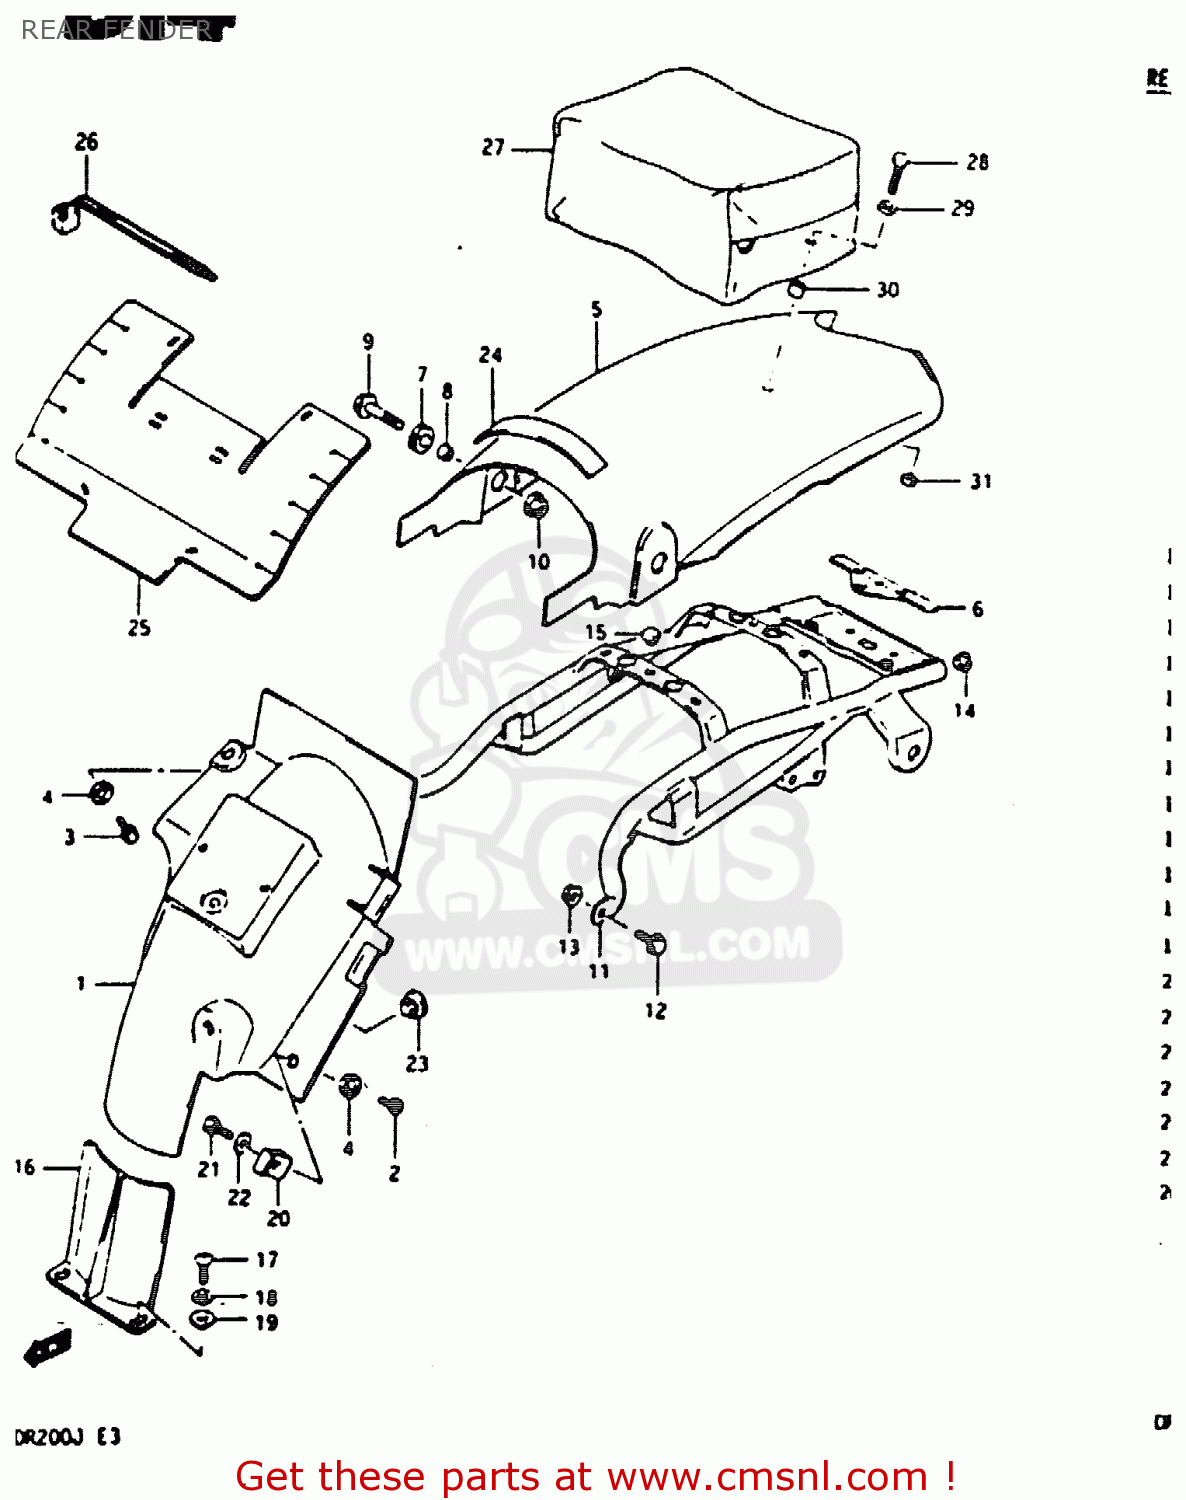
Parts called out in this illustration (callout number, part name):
1	BODY,RR FENDER FR
2	SCREW 6X12
3	BOLT 6X16
4	WASHER
5	FENDER,REAR
6	CUSHION,RR FENDER
7	CUSHION
8	SPACER (8.2X12X7.5)
9	BOLT
10	NUT
11	REINFORCEMENT,REAR FENDER
12	BOLT
13	NUT
14	PLUG
15	CUSHION
16	GUARD,RR UNIT MUD
17	SCREW
18	WASHER(6.5X16X1.2)
19	WASHER,LOCK
20	BRACKET,FENDER LOWER,LEFT
21	BOLT
22	WASHER (6.5X20X1.2)
23	CAP(OD:16)
24	CUSHION(25X185X15)
25	FLAP,AIR CLEANER MUD
26	CLAMP(L:125)
27	BAG ASSEMBLY,SEAT TAIL
28	BOLT
29	WASHER
30	SPACER (6.1X9X9)
31	NUT
